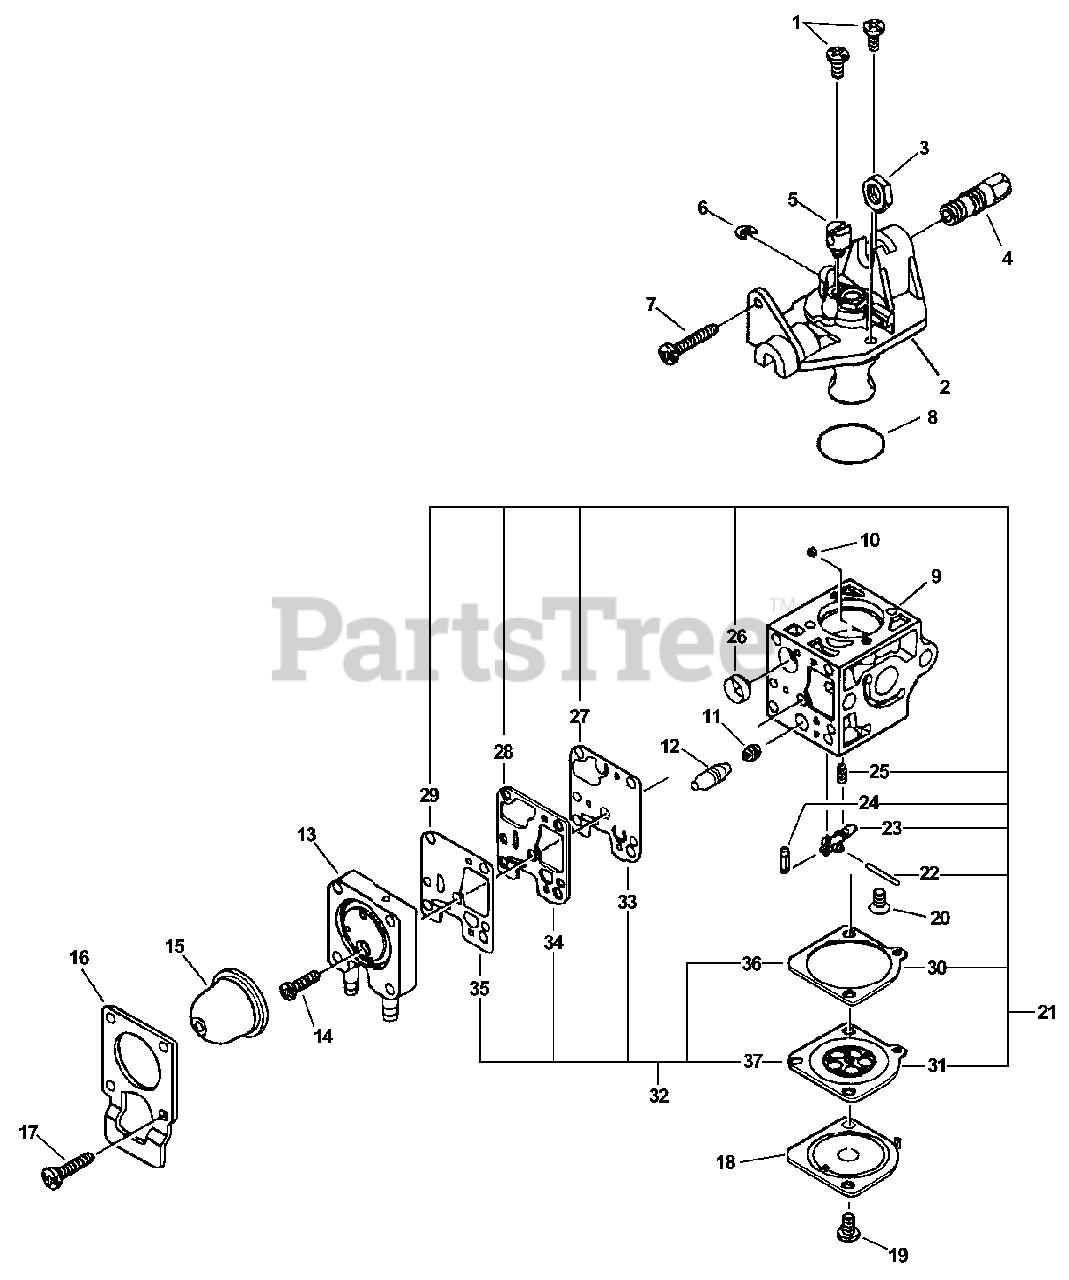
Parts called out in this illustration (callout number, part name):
2	ROTOR COVER ASSY
4	ADJUSTER, THROTTLE CABLE
7	SCREW, IDLE ADJUST
9	BODY, CARBURETOR
10	GUIDE, ROLLER
11	JET, MAIN
12	PLUG KIT
13	BASE, PURGE
15	BULB, PURGE
16	RETAINER, PURGE BULB
17	SCREW, PURGE BULB RETAINER
18	COVER, METERING DIAPHRAGM
21	REBUILD KIT
22	PIN, METERING LEVER
23	LEVER, METERING
24	VALVE, INLET NEEDLE
25	SPRING, METERING LEVER
26	STRAINER
27	DIAPHRAGM, PUMP
28	GASKET, PUMP
29	DIAPHRAGM, SURGE
30	GASKET, DIAPHRAGM
31	DIAPHRAGM, METERING
32	GASKET / DIAPHRAGM KIT
33	DIAPHRAGM, PUMP
34	GASKET, PUMP
35	DIAPHRAGM, SURGE
36	GASKET, DIAPHRAGM
37	DIAPHRAGM, METERING
